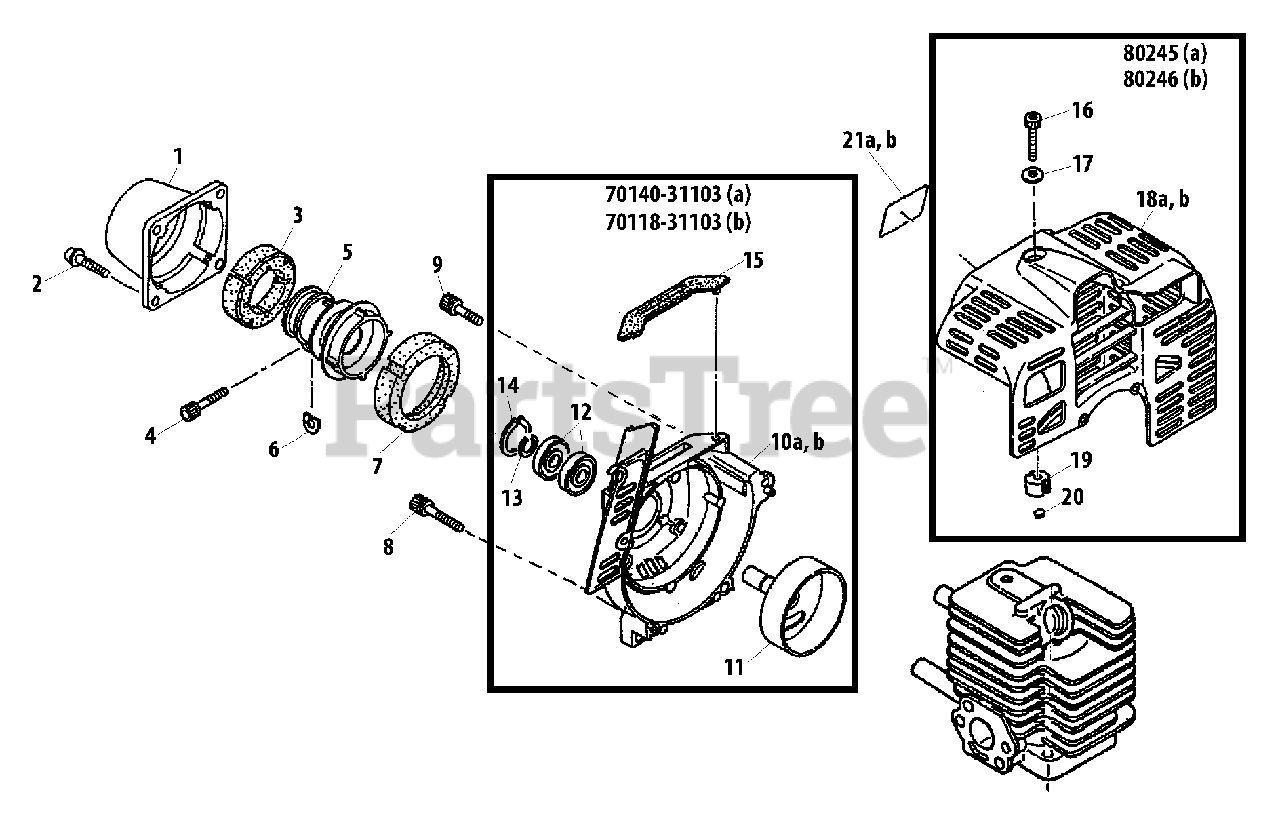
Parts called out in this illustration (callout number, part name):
1	CAP
2	SCREW - 5X16
3	CUSHION - FRONT
4	SCREW - 5X25
5	CLAMP, MAIN PIPE
6	SHIM
7	CUSHION - REAR
8	SCREW - 5X35
9	SCREW - 5X16
10A	CASE, FAN
10B	CASE, FAN
11	DRUM, CLUTCH
12	BEARING, BALL - 6000
13	RING, RETAINING
14	RING, RETAINING - 26
15	CUSHION
16	SCREW - 5X25
17	WASHER - 5
18A	COVER, ENGINE - RED
18B	COVER, ENGINE - BLUE
19	INSULATOR
20	CLIP
21A	LABEL - MODEL
21B	LABEL - MODEL
70118-31103B	FAN CASE ASSY
70140-31103A	FAN CASE ASSY
80245A	ENGINE COVER KIT - RED
80246B	ENGINE COVER KIT - BLUE
